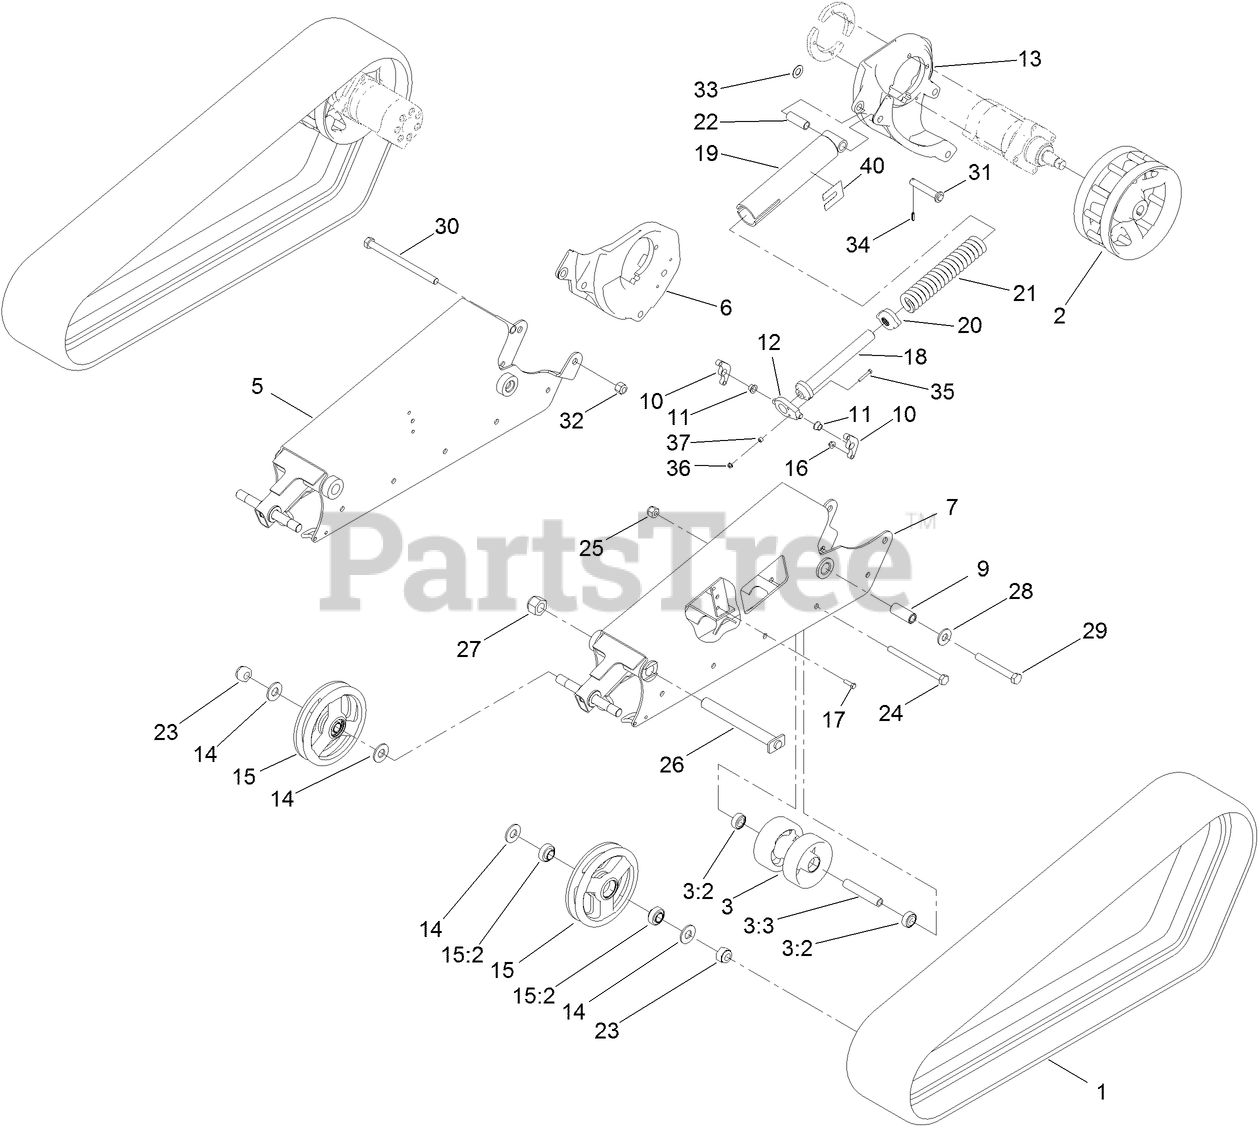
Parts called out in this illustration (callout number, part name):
1	TRACK-WIDE
2	WHEEL-DRIVE
3	ROAD WHEEL ASM
3:2	BEARING-BALL
3:3	SPACER-WHEEL, ROAD
5	FRAME-TRACK, RH
6	MOUNT-MOTOR, RH
7	FRAME-TRACK, LH
9	SPACER
10	PLATE-MOUNT, PIVOT
11	BUSHING-BELLCRANK
12	PLATE-PIVOT
13	MOUNT-MOTOR, LH
14	WASHER-PLAIN
15	Tensioner Wheel ASM
15:2	Bearing-Ball
16	NUT-HF, NI
17	SCREW-HH
18	BOLT-TENSIONER
19	PIVOT-TENSIONER
20	BLOCK-TENSIONER
21	SPRING-COMPRESSION
22	SPACER-PIVOT
23	NUT-HEX, NI
24	SCREW-HH
25	NUT-HEX
26	PIN-TRACK
27	NUT-HH
28	WASHER
29	SCREW-HH
30	BOLT-HH
31	PIN-TENSIONER
32	NUT-LOCK, NI
33	WASHER-FLAT
34	PIN-SPRING
35	SCREW-HH
36	NUT-HHF
37	SPACER
40	DECAL-INDICATOR, TENSIONER
